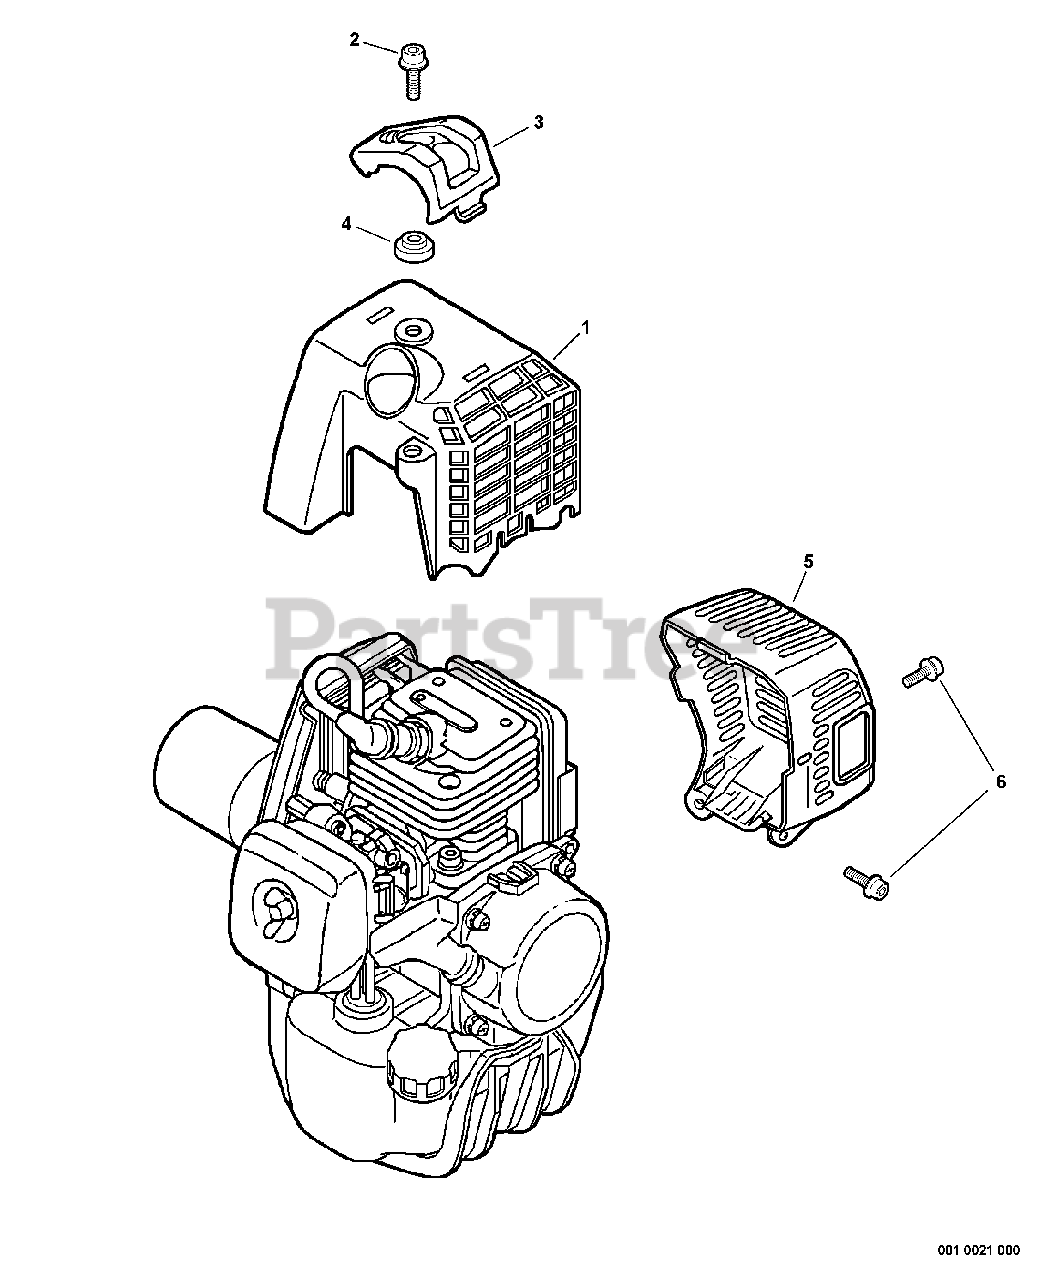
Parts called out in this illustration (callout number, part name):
1	COVER, ENGINE - ORANGE
2	SCREW - 5X16
3	GUARD - TOP
4	COLLAR - 5
5	COVER, EXHAUST
6	SCREW - 5X12
